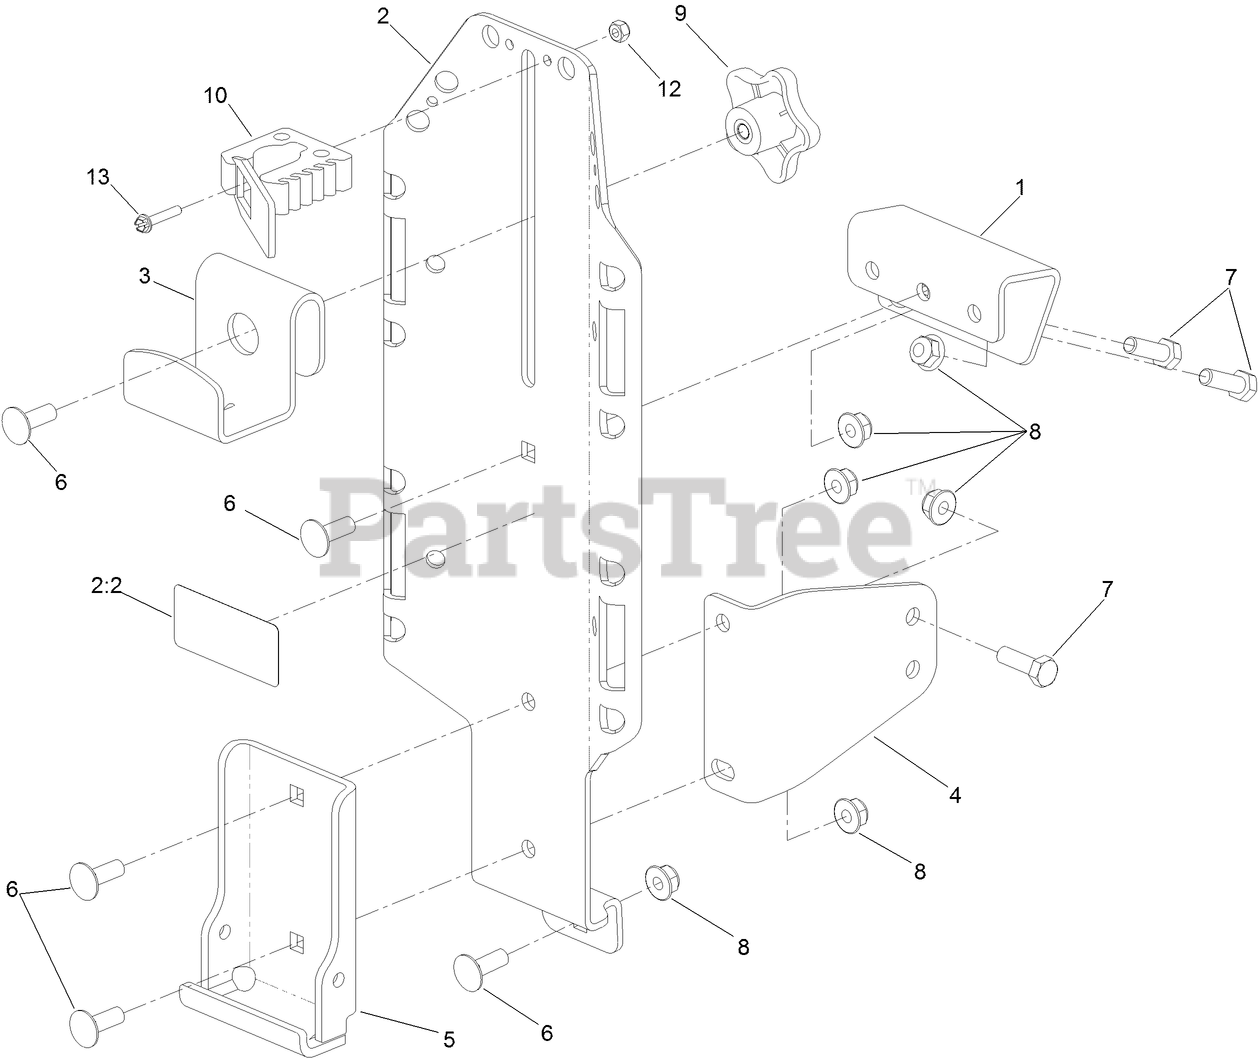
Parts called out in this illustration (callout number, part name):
1	MOUNT-BUCKET, UPPER
2	MOUNT BRACKET ASM
2:2	DECAL-WEIGHT, MAXIMUM
3	BRACKET-TOP
4	BRACKET-SUPPORT, LOWER
5	BRACKET-SUPPORT, HINGE
6	BOLT-CARR
7	SCREW-HH
8	NUT-HF, NI
9	KNOB-HANDLE
10	CLAMP-QUICK FIST, MINI
12	NUT-LOCK
13	SCREW-SHWH
